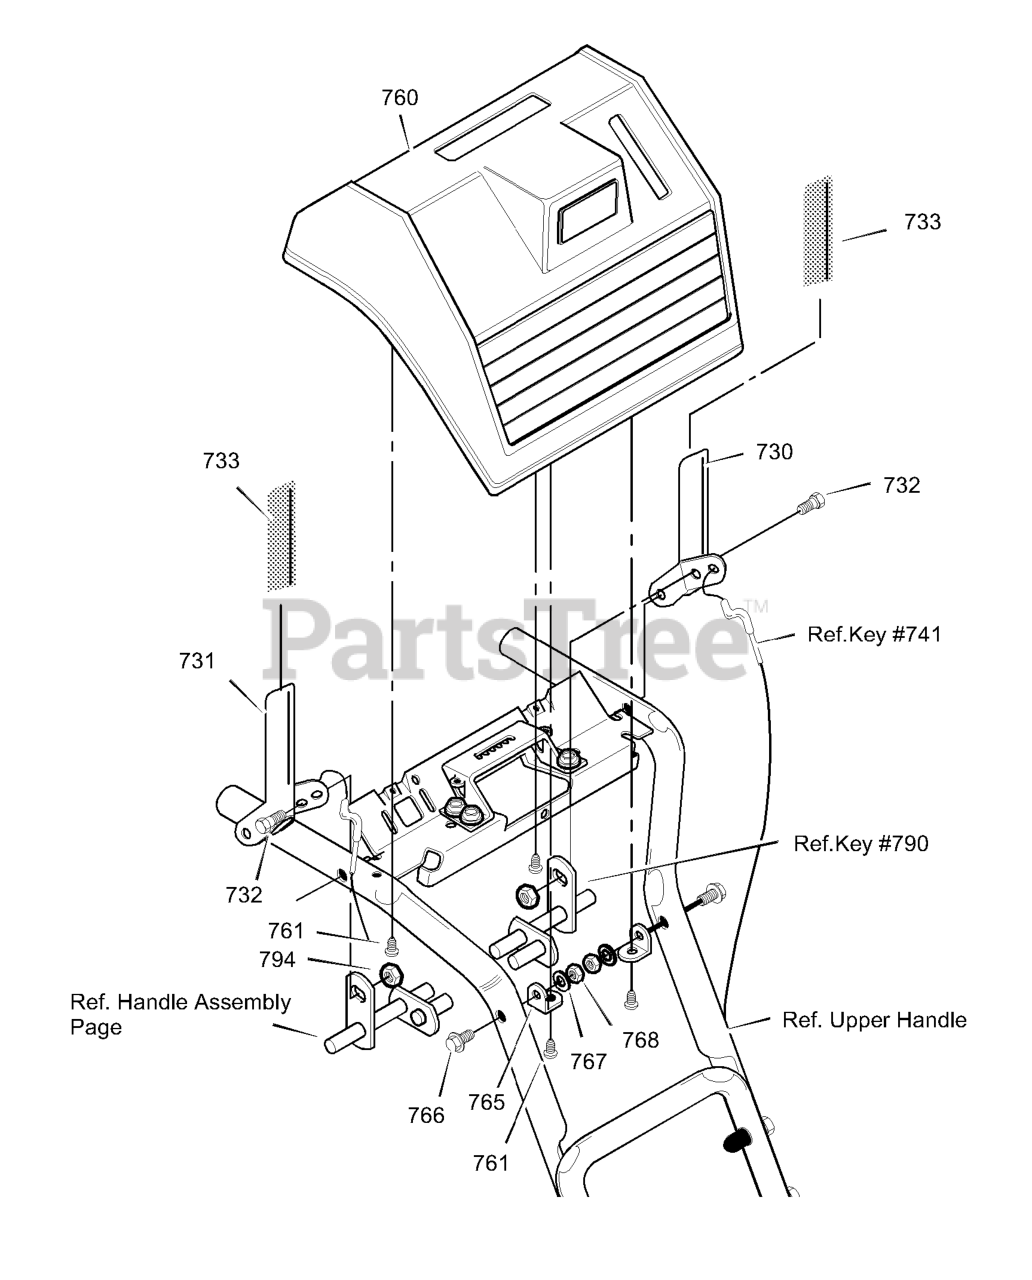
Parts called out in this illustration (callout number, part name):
730	CLUTCH HANDLE LH
731	CLUTCH HANDLE RH
732	BOLT, 1/4-20 X .50
733	GRIP, CLUTCH HANDLE
760	PANEL, CONTROL
761	SCREW, 10 X .62
765	BRACKET, PANEL
766	SCREW, 5/16-18 x 1.75
767	WASHER, HVSPTLK
768	NUT, 5/16-18
794	NUT, 1/4-20
